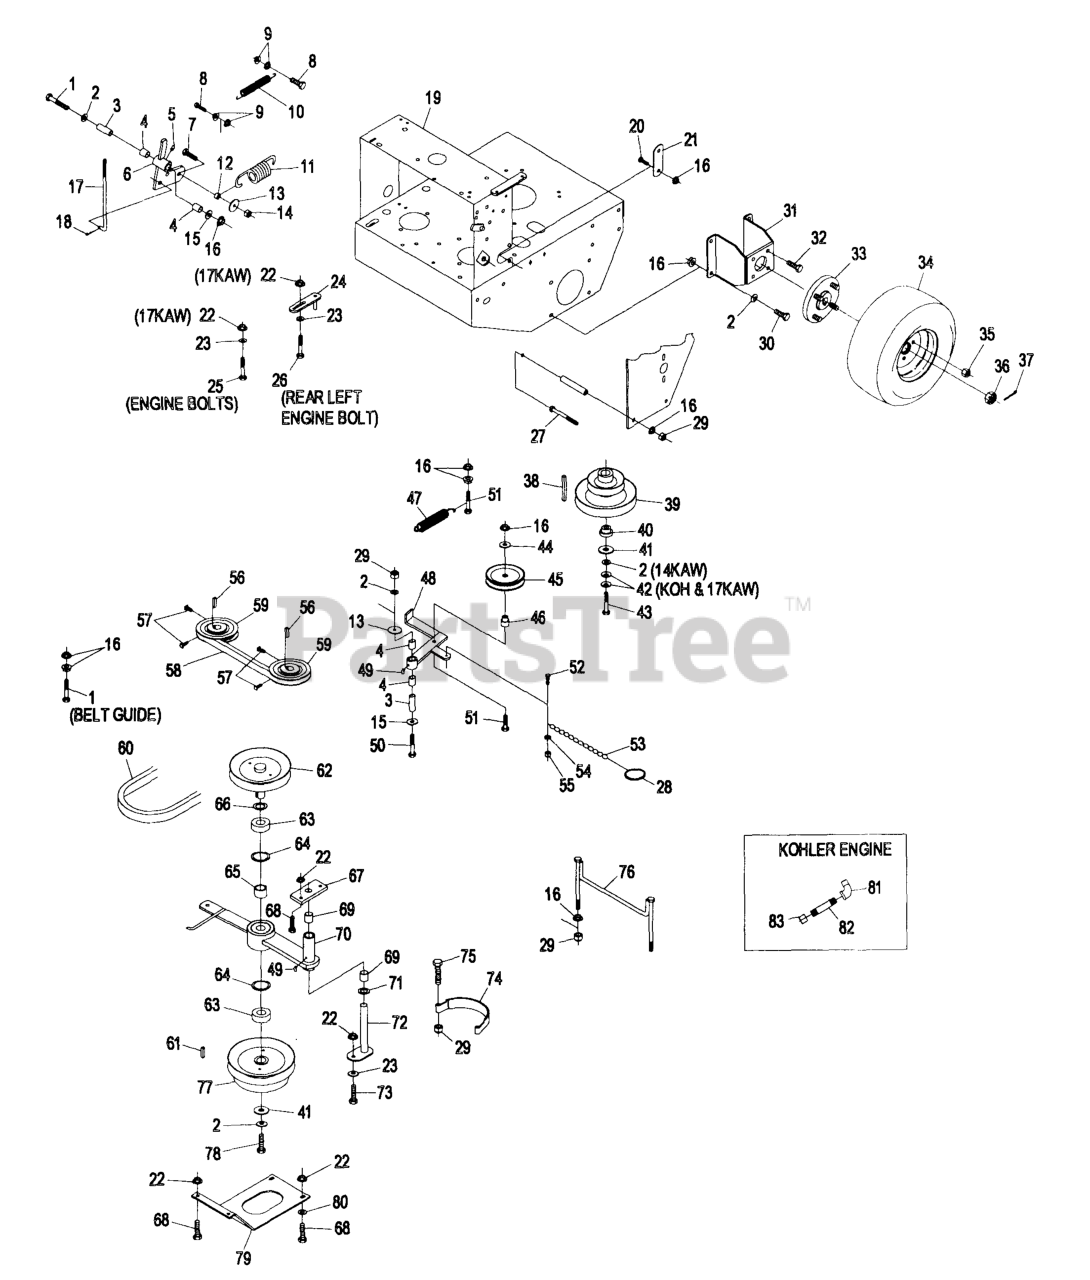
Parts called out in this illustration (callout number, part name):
3	BUSHING
4	SLEEVE-BEARING
10	SPRING,EXTENSION
11	SPRING,BELT TENSION
12	SPACER,CLUTCH ANCHOR
17	LINKAGE,LOWER
18	PIN-COTTER
21	ARM-LIFT, DECK
23	WASHER-SPRING
24	GUIDE-BELT
28	RING-SPLIT
31	WLD,MOTOR MOUNT 36
34	WHEEL AND TIRE ASM
37	PIN-COTTER
38	KEY,MACH 1/4X1/4X2-5/8
39	SHEAVE,DRIVE
40	BUSHING,CLUTCH KEEPER
42	WASHER-SPRING
43	SCRW,CAP HH
46	BUSHING-IDLER
47	SPRING-EXTENSION
49	1481
52	SCREW-HSH
53	CHAIN-LINK, TWIST
57	SCREW-SET
59	SHEAVE ASM
60	BELT,BLADE CLUTCH
62	SHEAVE,6.13 W/SHAFT
63	BEARING,CLUTCH SHAFT
65	SPACER,CLUTCH BEARING
66	WASHER-SPACER
67	PLATE-CLUTCH PIVOT
69	SLEEVE,BEARING
71	WASHER-SPACER
72	WLD,PIN PIVOT
74	BAND,BRAKE BLADE
76	GUIDE - BELT
77	SHEAVE,6.13 W/HUB
78	SCRW,CAP HH
79	PLATE-GUARD
81	FITTING-ELBOW-90
82	NIPPLE
83	CAP-HEX
